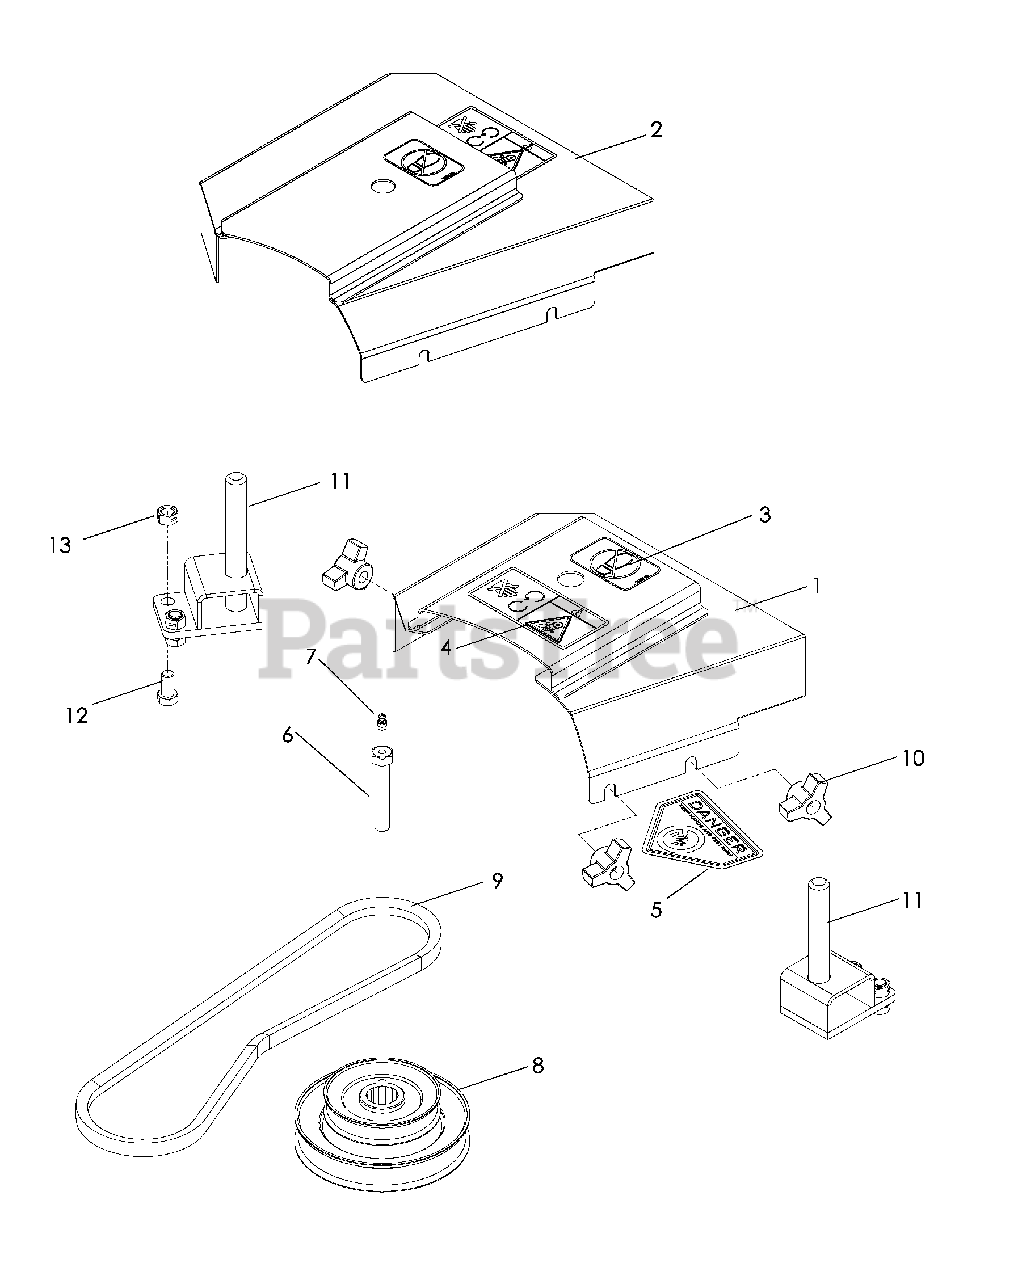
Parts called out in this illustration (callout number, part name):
1	SHIELD W/DECALS 52"
2	SHIELD W/DECALS 61"
3	DECAL, NO STEP
4	DECAL, BELT DRIVE
5	DECAL, CPSC
6	HCS 7/16-20 x 2½ SPECIAL
7	ZERK
8	PULLEY, DBL STACKED 52"
9	PULLEY, DBL STACKED 61"
12	KNOB, THREE PRONG
13	BLOWER PIN, SM
14	HCS 3/8-16 x ¾
15	NUT 3/8 -16 CENTERLOCK
